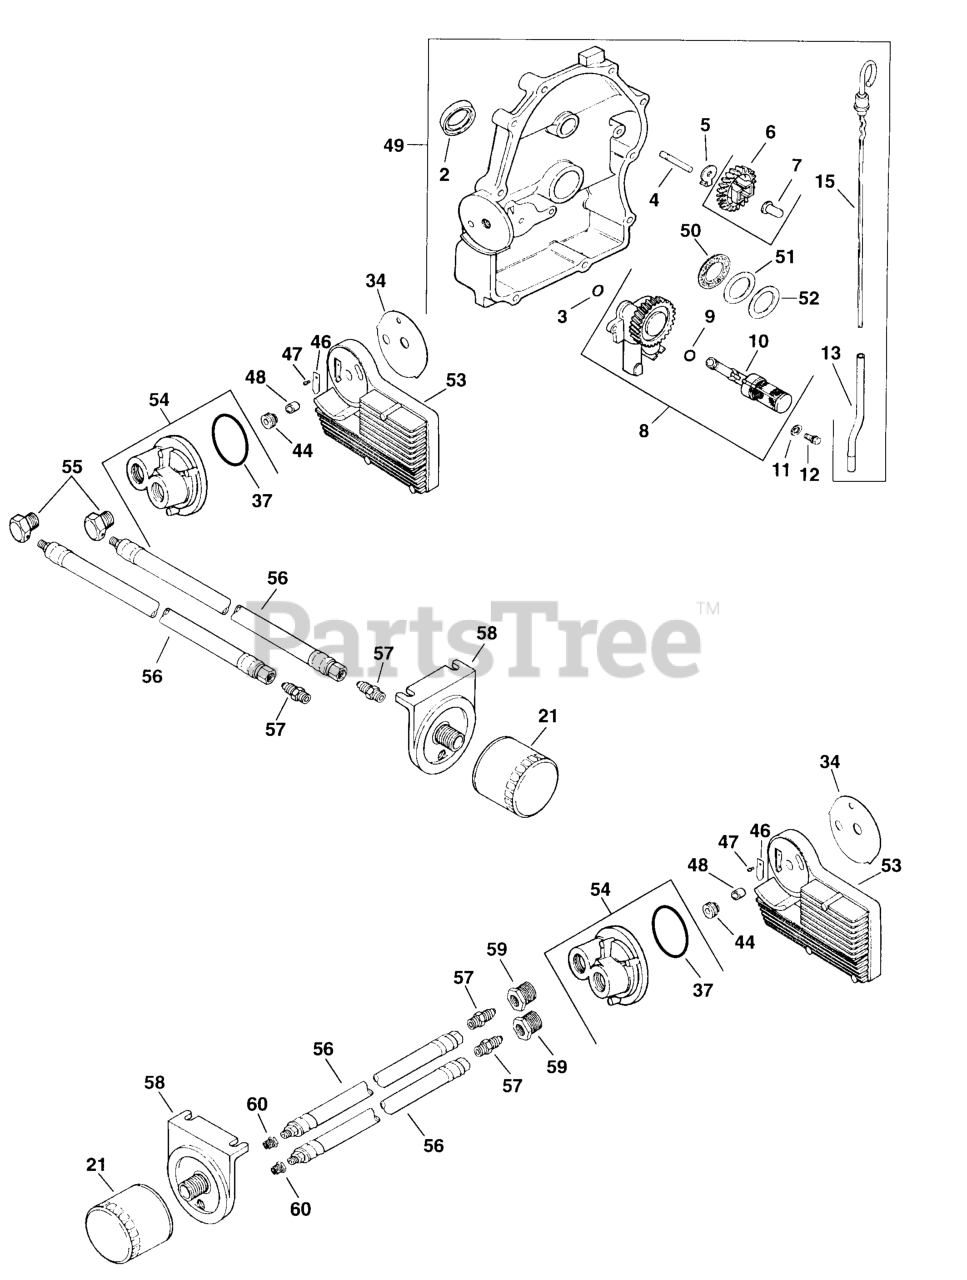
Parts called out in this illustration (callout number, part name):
2	SEAL, OIL (KM)-USE 25 032 06-S
4	SHAFT, GOVERNOR GEAR
6	KIT, GOVERNOR GEAR W/PIN
7	PIN, GOVERNOR REGULATING
8	PUMP, OIL - DISCONTINUED
9	O-RING, OIL PICK-UP
10	PICK-UP, OIL - DISCONTINUED
10	PICK-UP, OIL
11	WASHER - USE M-631005
12	SCREW - USE M-645025
21	OIL FILTER
34	GASKET - USE 24 041 29
46	REED, OIL RELIEF - DISCONTINUED
47	Screw, hex. cap M4x0.7x10
48	PIN - USE 12 380 17
49	KIT, CLOSURE PLATE USE 24 009 230-S
50	BEARING, THRUST
51	WASHER - USE 52 114 04
52	SHIM, THRUST (GREEN .875MM) - DISCONTINUED
52	SHIM, THRUST (BLUE .5MM)
